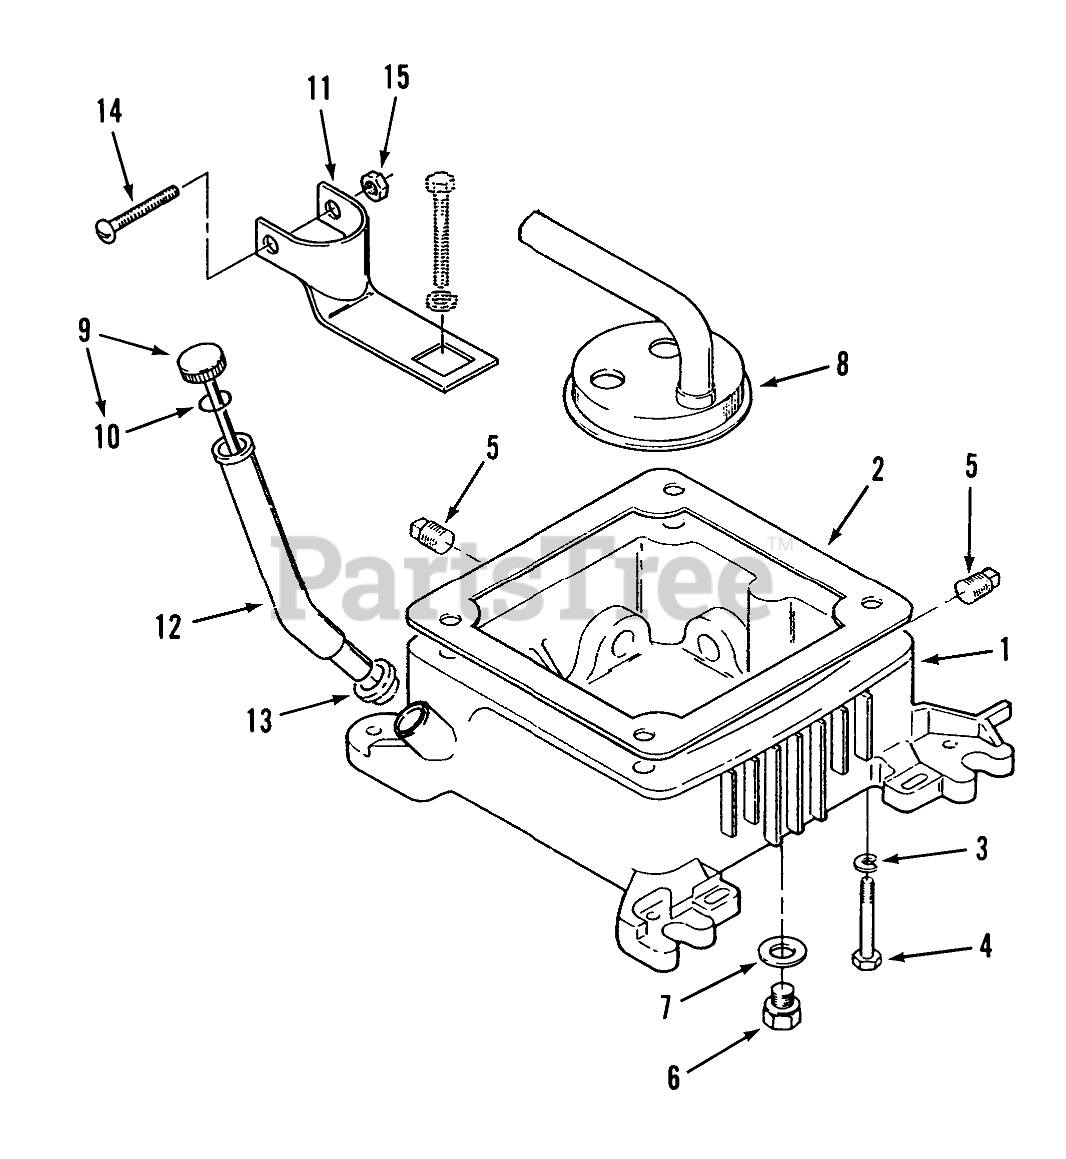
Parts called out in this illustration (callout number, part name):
1	Oil Base (Includes All Plugs and Plug Gasket)
2	Gasket
3	Lockwasher 3/8
4	HHCS 3/8-16 X 3 3/4
5	Plug
6	Plug
7	Gasket
8	Cup-Oil Pump Intake
9	Oil Fill Cap and Indicator (Includes "O" Ring)
10	O-Ring
11	FILL TUBE BRACKET
12	Oil Fill Tube-Chrome 15-3/4" Lg
13	Seal
14	Pan Hd. Screw #10 x 1-1/4
15	Nut
